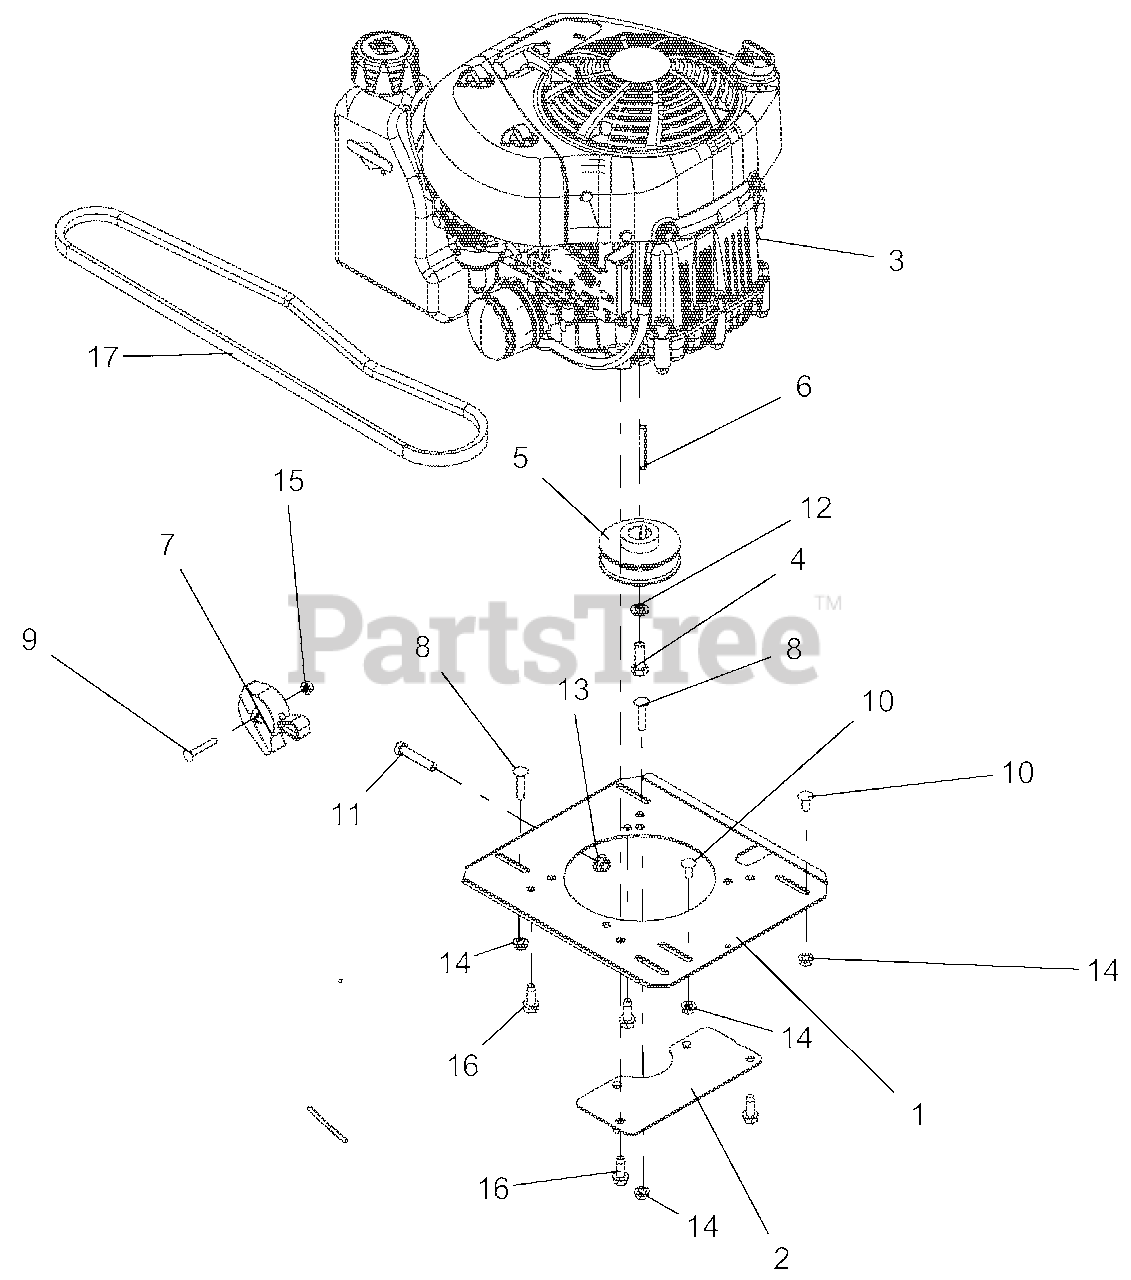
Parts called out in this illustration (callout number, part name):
1	PLATE-ENGINE MTG
2	WMT-HWM ENGINE BELT FINGER
3	ENGINE, B&S 10.5HP INTEK CARB
4	BLT-HEX .44-20X1.25 GR5 YWZC
5	WMT-SHEAVE, ENGINE HWM INTEK
6	KEY .25X.25X2.25
7	CABLE, THROTTLE, KILL & CHOKE
8	@BLT-RDHDSQNK .31-18X1.50 G5YZ
9	BLT-RDHDSQNK .25-20X1.75 G5YZ
10	@BLT-RHDSSQNK .31-18X.75 G5YZ
11	BLT-HEX .38-16X2.0 GR5 FTD YWZ
12	@WSHR-LK .44X.109 REG YWZC
13	@NUT-LK-NYL-FLG .38-16 YWZC
14	@NUT-LK-TOP-FLG .31-18 YWZC
15	@NUT-LK-TOP-FLG .25-20 YWZC
16	@SCR-TAP .38-16X1.00 HWH TR YZ
17	V-BELT, 5L-WRAPPED
